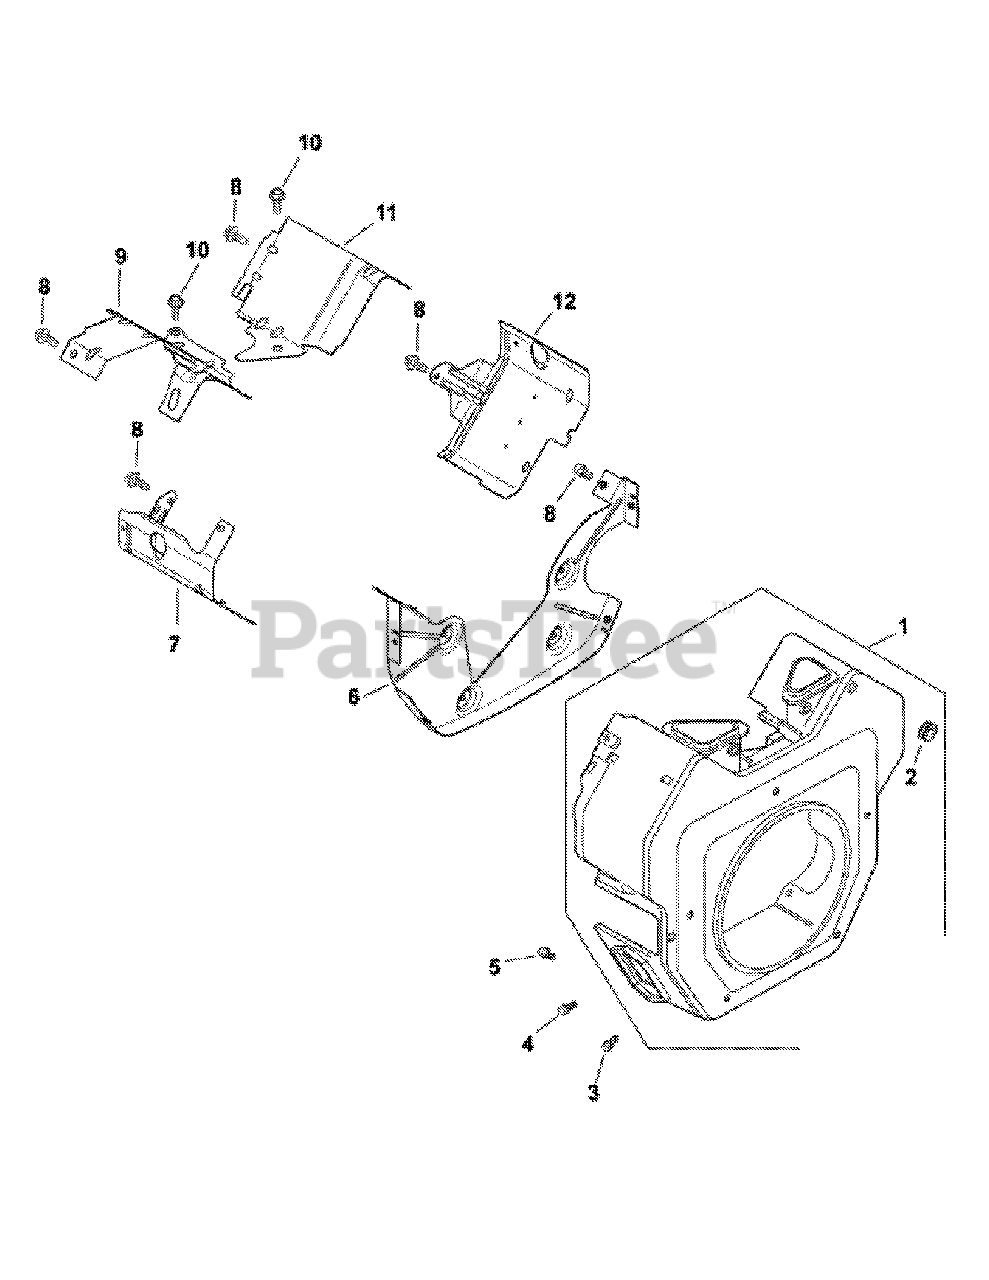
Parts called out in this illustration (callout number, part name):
1	Kit, Blower Housing (includes 2, 41 037 10-S)
3	Screw, Flg Thd Frm M5x.8x16
4	Screw, Flg Thd Frm M5x.08x16
5	Screw, Flg Thd Frm M6x1.0x20
6	Kit, Backing Plate
7	Kit, Cylinder Baffel #1 Side
8	Screw, Flg Thd Frm M6x1.0x16
9	Baffle, Valley #2 Side
10	Screw, Flg Thd Frm M5x.8x10
11	Baffle, Valley #1 Side
12	Kit, Cylinder Baffel #2 Side
